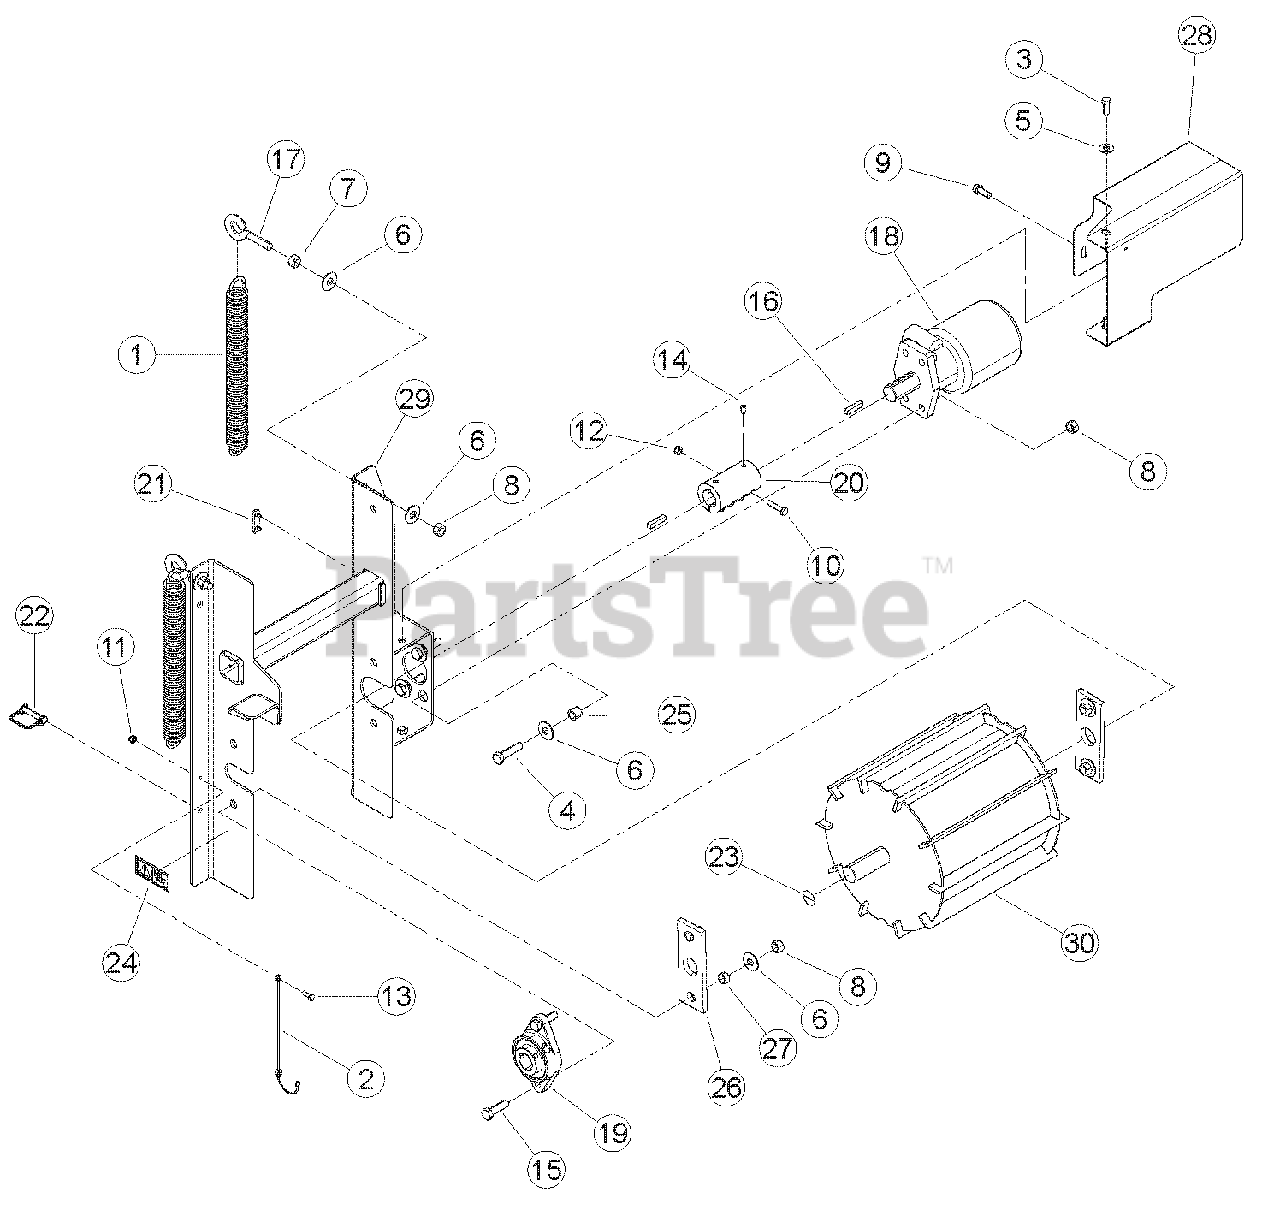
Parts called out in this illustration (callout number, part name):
1	SPRING, EXTENSION
2	LANYARD, NYLON
3	BOLT, 3/8 NC X 1 HEX HD GR5 ZP
4	BOLT, 1/2 X 2 HEX HD
5	WASHER, 3/8 FLAT ZP
6	WASHER, 1/2 FLAT ZP
7	NUT, 1/2 HEX NC ZP
8	NUT, 1/2 CENTERLOCK GRB ZP
9	BOLT, 3/8 X 1 THREAD CUT
10	BOLT, 5/16 X 1-1/2 HEX HD
11	NUT, 1/4 NYLOCK
12	NUT, 5/16 NYLOCK
13	BOLT, 1/4 X 3/4 HHCS GR5 NF ZP
14	SETSCREW, 3/8-16 X 1/2 SET
15	BOLT, 1/2 X 1-3/4 HEX HD
16	KEY, 5/16 X 1-3/4 SQUARE
17	I-BOLT, 1/2 X 2
18	MOTOR, 45 CU. IN. HYDRAULIC
19	BEARING, 1-1/4 2 BOLT FLANGE
20	COUPLER, 1-1/4 SHAFT
21	WEAR PAD, STD. SPRING HD FRONT
22	PIN, 3/8 X 1-1/2 SNAP
23	DECAL, ROTATING SHAFT
24	DECAL, CRUSHING ISO
25	SPACER, .75 X .62
26	BEARING, ROLLER SLIDE
27	SPACER, .75 OD X .37
28	WELDMENT, MOTOR COVER
29	WELDMENT, ROLLERSLIDE
30	WELDMENT, FEED ROLLER
